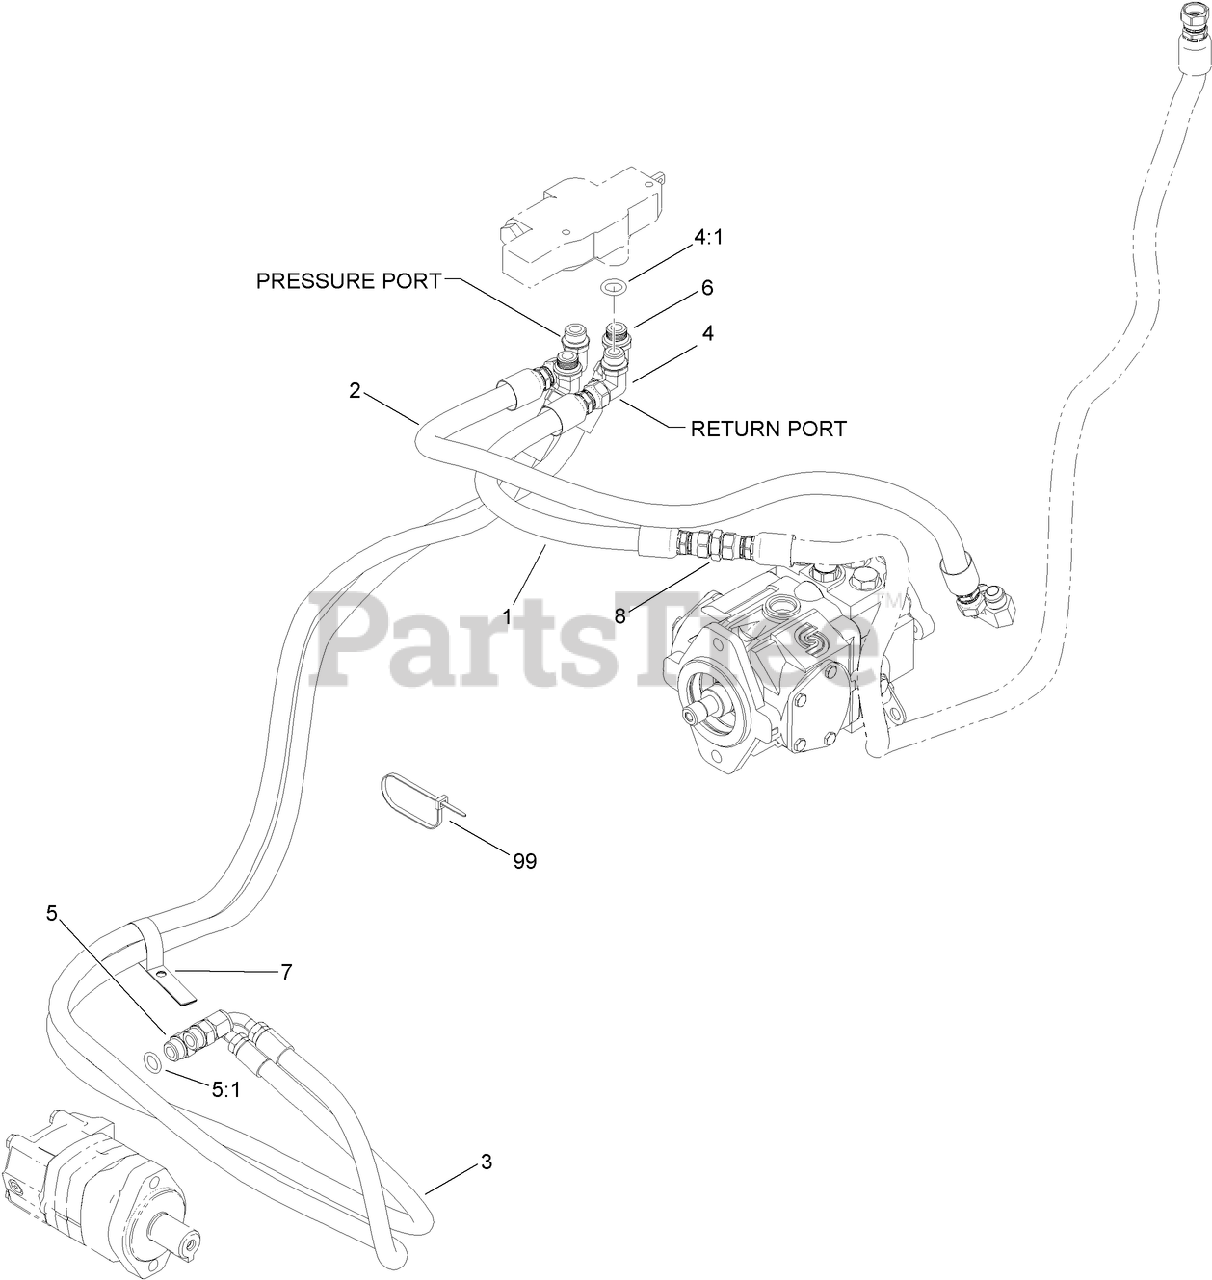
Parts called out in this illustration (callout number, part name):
1	HYD HOSE ASM
2	HOSE ASM
3	HYD HOSE ASM
4	FITTING-ELBOW, 90 DEG
4:1	O-RING
5	FITTING-STRAIGHT
5:1	O-RING
6	FITTING-ELBOW, 45 DEG
8	FITTING-UNION
99	STRAP-TIE
